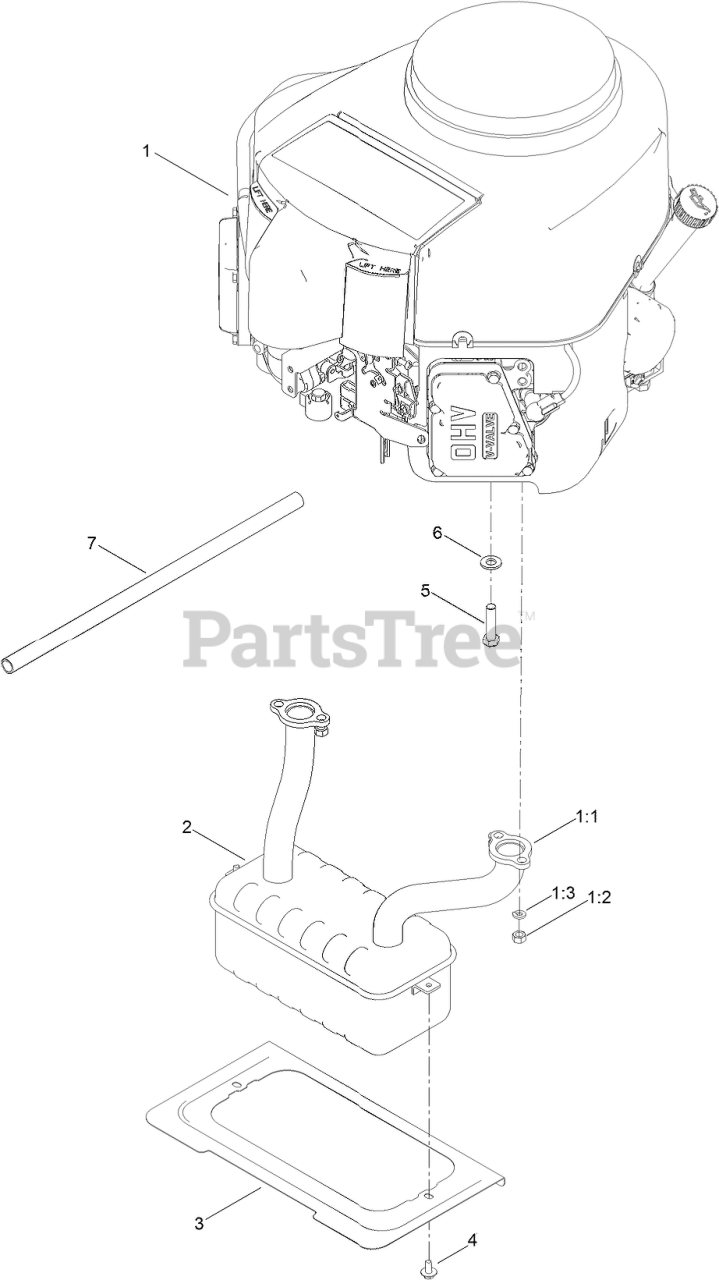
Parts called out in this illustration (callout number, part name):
1:1	GASKET-EXHAUST
1:3	WASHER-LOCK
2	MUFFLER
3	SHIELD-HEAT
4	SCREW-HHFTF
5	BOLT-HH
6	WASHER-FLAT
7	TUBE-DRAIN, OIL
